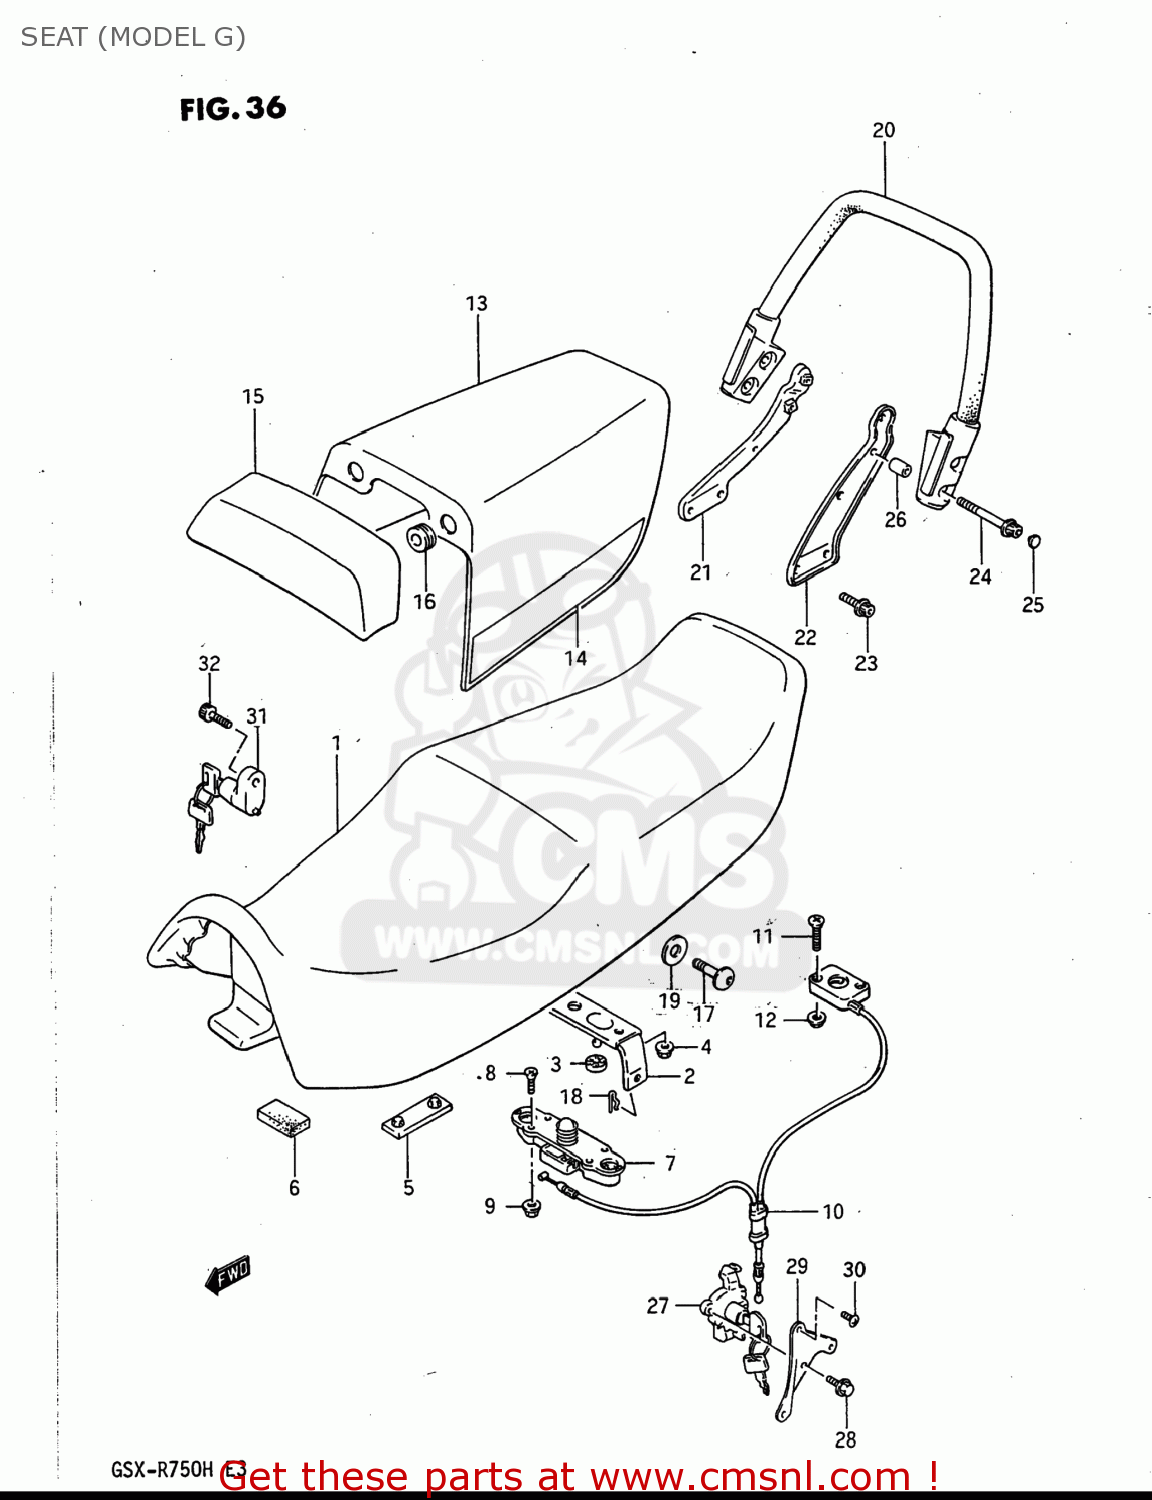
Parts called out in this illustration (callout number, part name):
1	SEAT ASSEMBLY
2	STRIKER,SEAT LOCK
3	CUSHION
4	NUT
5	CUSHION
6	CUSHION
7	LOCK ASSY,SEAT STRIKER
8	SCREW
9	NUT
10	BRACKET,SEAT SUPPORT RR
11	SCREW
12	NUT
13	BOX,SEAT TAIL
14	TAPE SET,SEAT TAIL BOX
15	BACKREST,SEAT
16	CUSHION
17	BOLT
18	CLIP
19	WASHER(10.1X25X3.2)
20	HANDLE,PILLION RIDER
21	PLATE,PILLION HANDLE,R
22	PLATE COMP,PILLION HANDLE
23	BOLT
24	BOLT
25	CAP(OD:10)
26	SPACER (8.6X13.8X21.5)
27	LOCK SET
28	PLUG ,6X20
29	BRACKET,SEAT LOCK
30	SCREW 6X12
31	LOCK SET
32	BOLT
